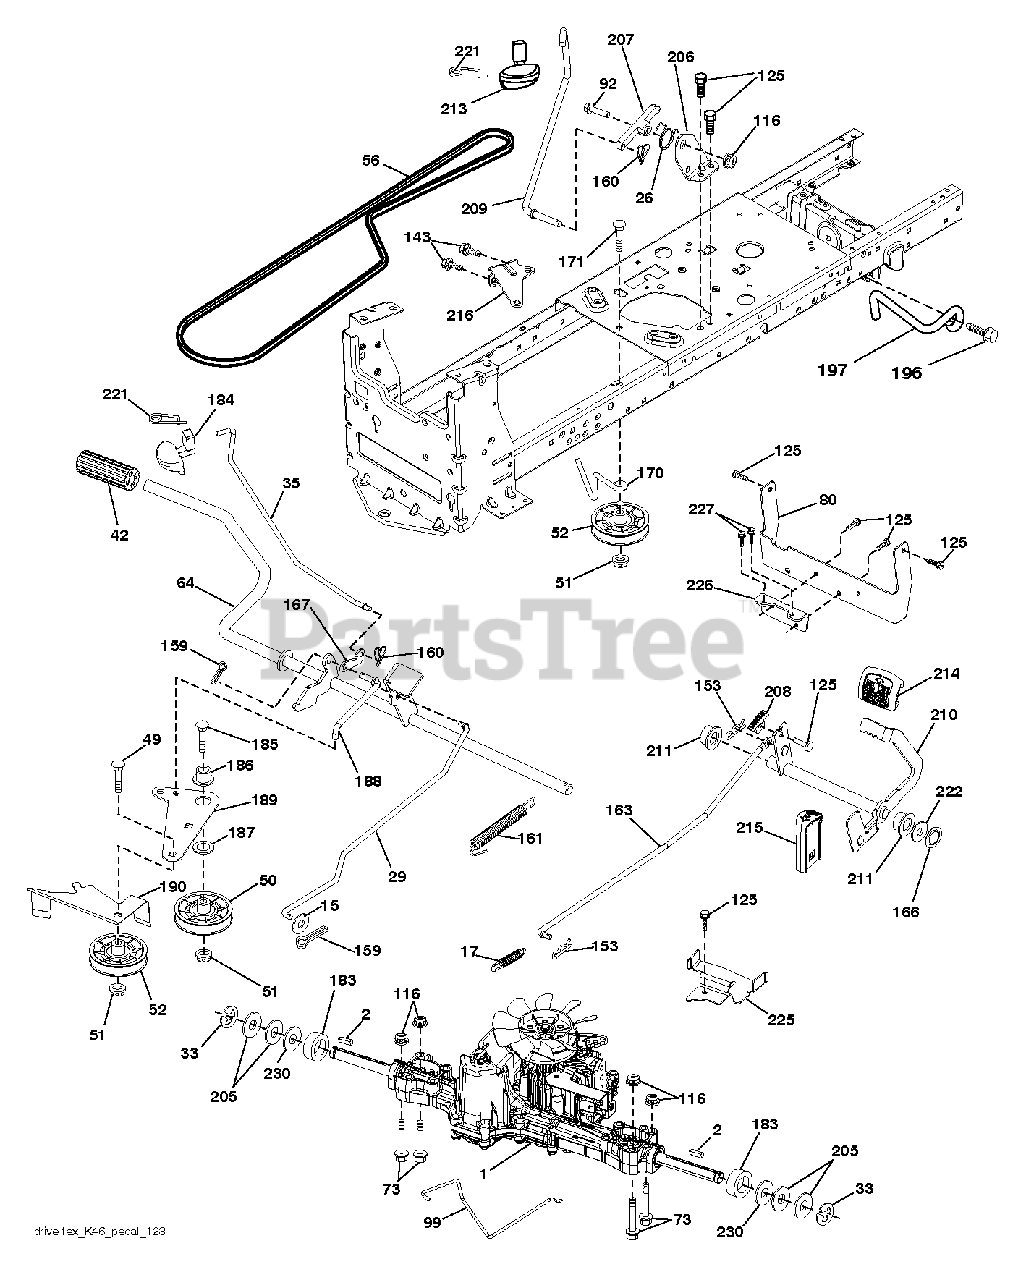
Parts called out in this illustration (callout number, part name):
2	SQUARE KEY
15	WASHER
17	SPRING.BRAKE.K46.GREEN
26	SPRING.RETURN.CRUISE
29	ROD.BRAKE.K46
35	ROD .BRAKE. PARKING. GT. HUSQ.
42	PEDAL COVER T
50	IDLER.FLAT.910.OFFSET
51	NUT LOCK FLG 3/8-16 UNC
52	IDLER.V-GROOVE.910.OFFSET
56	V-BELT.MOWER.92.40.42/K46
64	SHAFT.ASM.PEDAL.BRK.CNTR
80	STRAP.TORQUE.K46.K57R.TT
92	BOLT
99	ROD.SPRING.BYPASS.K46.LT.Z
116	NUT LOCK HEX FLANGE 5/16-18
125	SCREW
143	SCREW LT
153	RETAINER M
159	COTTER PIN
160	RETAINER CLIP
161	SPRING, RETURN LT
163	ROD.CONTROL.K57R.K46
166	NUT.PUSH.625
167	LATCH.BRAKE.SPRING
170	KEEPER.V-IDLER.CENTER.
183	SPACER AXLE
184	RB HANDLE.PARKG.BRK.HUS/PRED
186	SPACER.RETAINER
187	WASHER 12/32X2X10GA
188	RP LINK.CLUTCH.GROUND.DRIVE
189	BELLCRANK.GROUND.DRIVE.TEX.
190	KEEPER.BELLCRANK.DRIVE
196	SCREW 3/8-16X1
197	LINK.CLUTCH.ANIT-ROTAT
206	BRACKET.MOUNT.CRUISE.LATCH
207	LATCH.CONTROL.CRUISE
208	GEAR.SECTOR.CONTROL.CR
209	ROD.CONTROL.CRUISE.GT.
210	ROCKER.ASM.PEDAL.CONTR
211	BEARING.NYLON
213	KNOB.CONTROL.CRUSIE.HU
214	PEDAL.FORWARD.PAD.TEX
215	PEDAL.REVERSE.TEX.GT.4
216	BRACKET.PULLEY.IDLER.W/TEX
221	RETAINER.SPRING.CLIP.H
222	WASHER 21/32 X 1-1/4 X 10 GA.
225	KEEPER.BELT.TRANSAXLE.K46
226	BRACKET.MOUNT.TORQUE.K46.TLT
227	SCREW
230	WASHER.HARDENED
